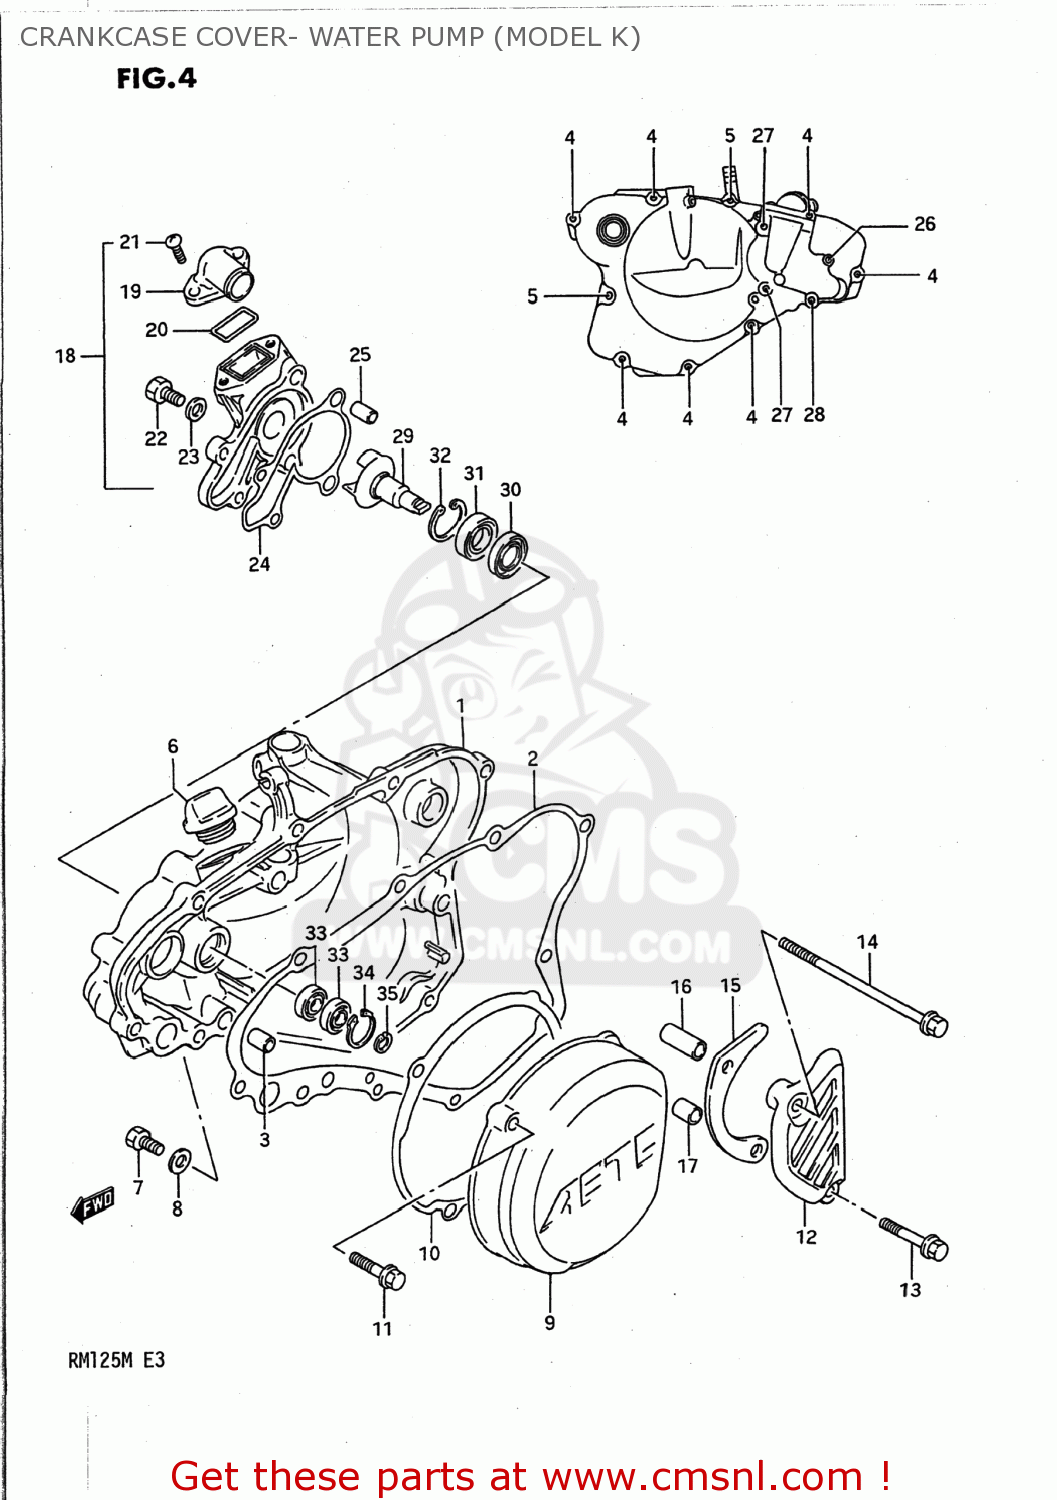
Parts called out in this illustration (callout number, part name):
1	COVER,CLUTCH
2	GASKET,CLUTCH COVER (NAS)
3	PIN
4	BOLT
5	BOLT
6	PLUG SET
7	SCREW(6X10)
8	GASKET(6.2X11X1).2 (NAS)
9	COVER,MAGNETO
10	GASKET,MAGNETO COVER (MCA)
11	BOLT
12	COVER,SPROCKET
13	BOLT
14	BOLT(6X105)
15	PLATE,FR CHAIN GUIDE
16	SPACER(6.5X10.5X25)
17	SPACER(6.5X10.5X12)
18	CASE ASSEMBLY,WATER PUMP
19	CONNECTOR
20	O RING,WATER PUMP CONNECTOR
21	SCREW
22	BOLT,BLEEDER
23	GASKET (NAS)
24	GASKET,WATER PUMP CASE (NAS)
25	PIN
26	BOLT
27	BOLT
28	BOLT
29	IMPELLER,WATER PUMP
30	SEAL,OIL(12X24X3.6)
31	SEAL,OIL(12X24X6.4)
32	CIRCLIP
33	BEARING
34	CIRCLIP
35	CIRCLIP
